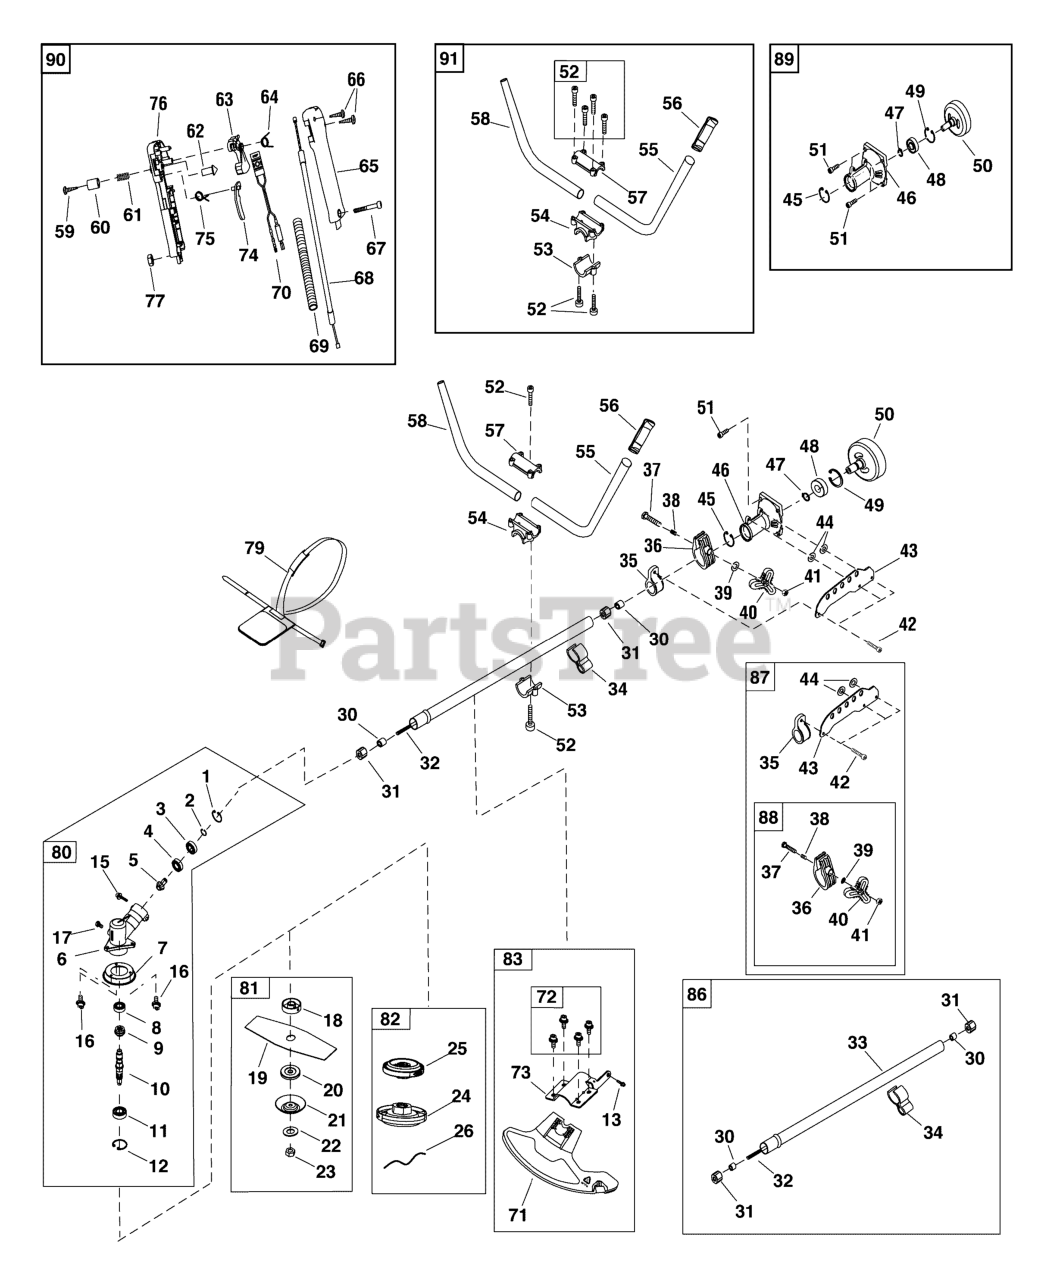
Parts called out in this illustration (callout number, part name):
5	PINION
6	GEAR BOX
7	COVER, Blade
10	SPLINE SHAFT
17	BOLT, M8 x 12
18	GASKET, Spline
19	BLADE, Two Teeth
20	HOLDER
21	PROTECTOR, Blade
22	WASHER, Wave, Dia 10
24	CAST HEAD, Straight Shaft
25	COVER, Alloy Head
26	TRIMMER LINE (10 Pack)
30	BEARING, Oil
31	RUBBER COVER, Bearing Oil
32	DRIVE SHAFT
33	SHAFT, Straight
34	RETAINER, Wire
35	RING, Hang
36	RING FOR LIMIT
37	* BOLT, Hex Head
38	SPRING
40	HANDLE, Self Lock
41	* NUT, Hex Head
43	HANG HANDLE
44	SPACER, Hang Handle
46	CASE, Clutch
50	CLUTCH DRUM, Complete
53	BRACKET, Shaft, Lower
54	BRACKET, Shaft, Upper
55	HANDLE, Left
56	GRIP, Handle
57	HANDLE, Mounting, Upper
58	HANDLE, Right
59	SCREW, ST 2.9 x 13
60	BUTTON, Speed Lock
61	SPRING, Speed Lock
62	PIN, Clock
63	TRIGGER, Presence
65	COVER, Throttle
66	SCREW, ST 2.9 x 18
68	CABLE, Comp.
69	COVER, Cable
70	STOP BUTTON ASSEMBLY
71	SAFETY GUARD
73	HOLDER, Safety
74	TRIGGER, Throttle
76	COVER, Throttle
80	KIT, Gear Box Assembly
81	KIT, Blade Assembly
82	KIT, Alloy Head
83	KIT, Safety Guard
86	KIT, Drive Shaft Assembly, SP
87	KIT, Hang Handle Assembly
88	KIT, Limit Ring Assembly
89	KIT, Clutch Assembly
90	KIT, Throttle Assembly, B&S SP
91	KIT, Handle Assembly
